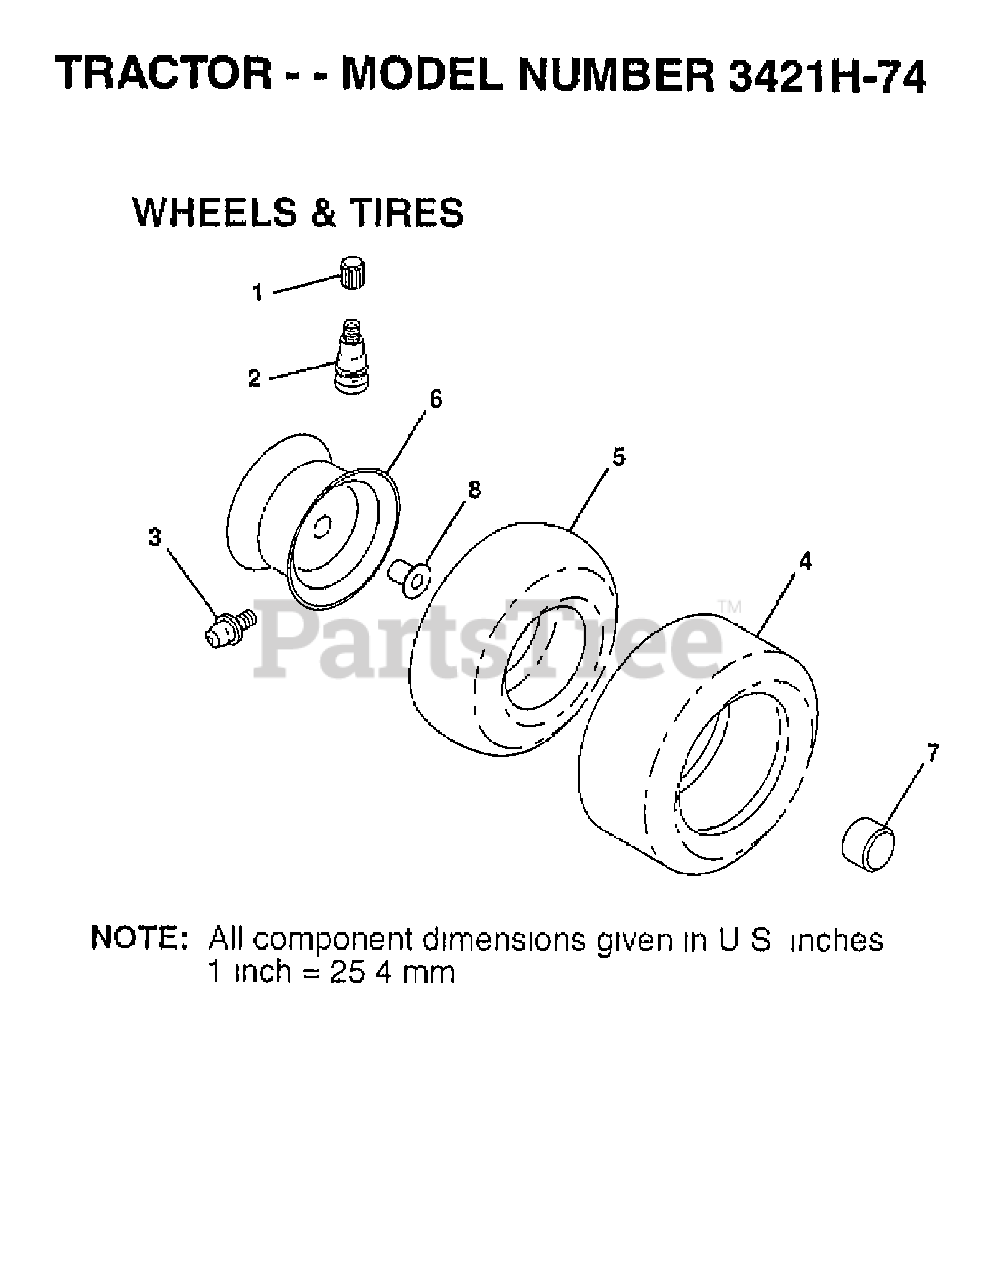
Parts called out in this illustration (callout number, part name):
1	VALVE CAP
2	VALVE STEM LT
3	FITTING LT
4	TIRE HEAVY DUTY
4A	TIRE 20X8-8 TURF SAVER
5	TUBE.5.3/4.5/6
5A	TUBE - UNIVERSAL FOR 8" RIM
6	RIM.ASM.6".FRONT.SILVER
6A	RIM 8" SILVER
7	CAP.HUB.FRONT.LT.BLACK
8	BEARING T
